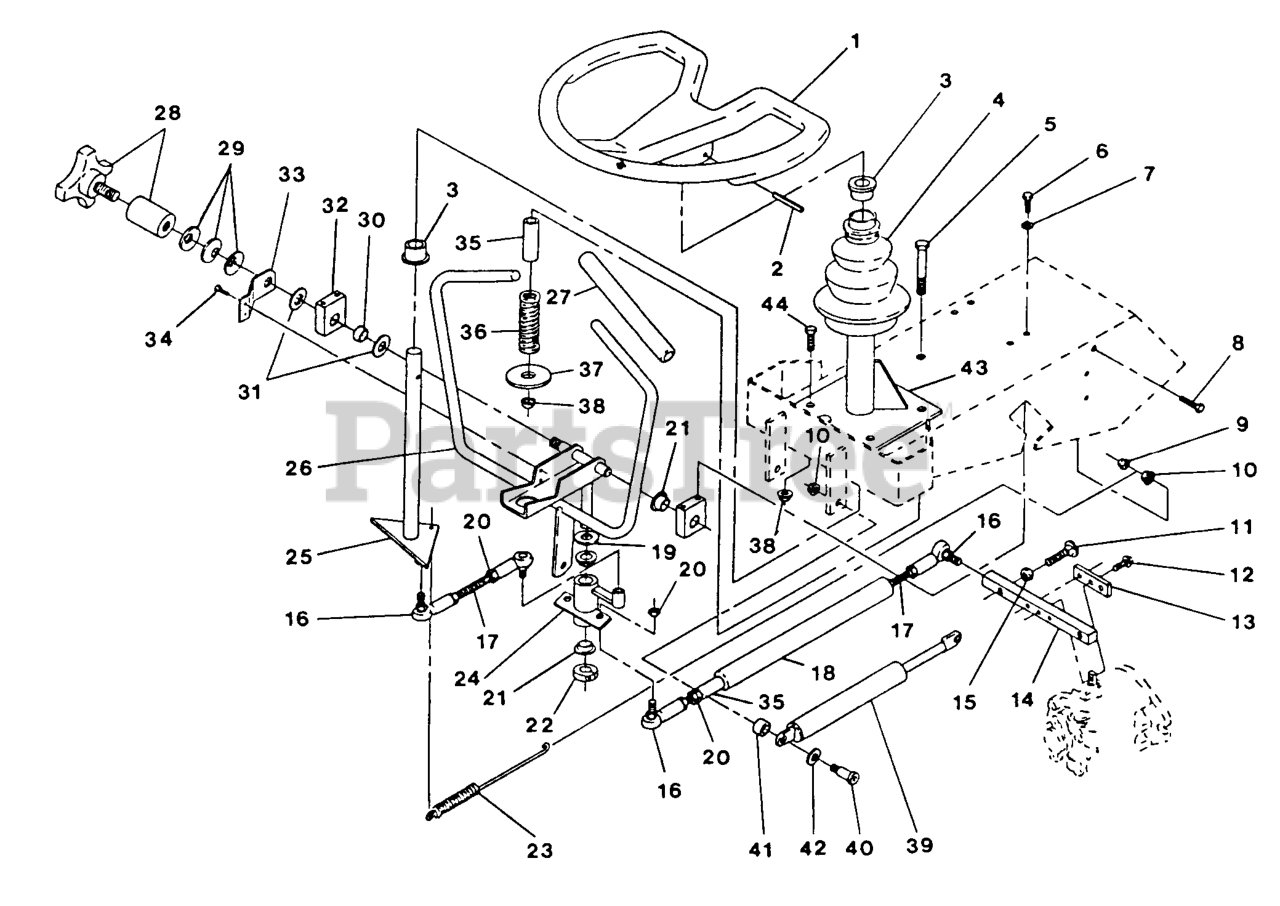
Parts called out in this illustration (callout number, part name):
7	WASHER-LOCK
13	PLATE,CLAMP
14	ARM,PUMP CONTROL
16	BALLJOINT
17	ROD,STEERING
21	BEARING-CONTROL
30	BEARING,CONTROL MOUNT
35	BUSHING,SPRING GUIDE
36	SPRING-INDICATOR, REVERSE
37	WSHR,REVERSE INDICATOR
41	SPACER-PLATED
